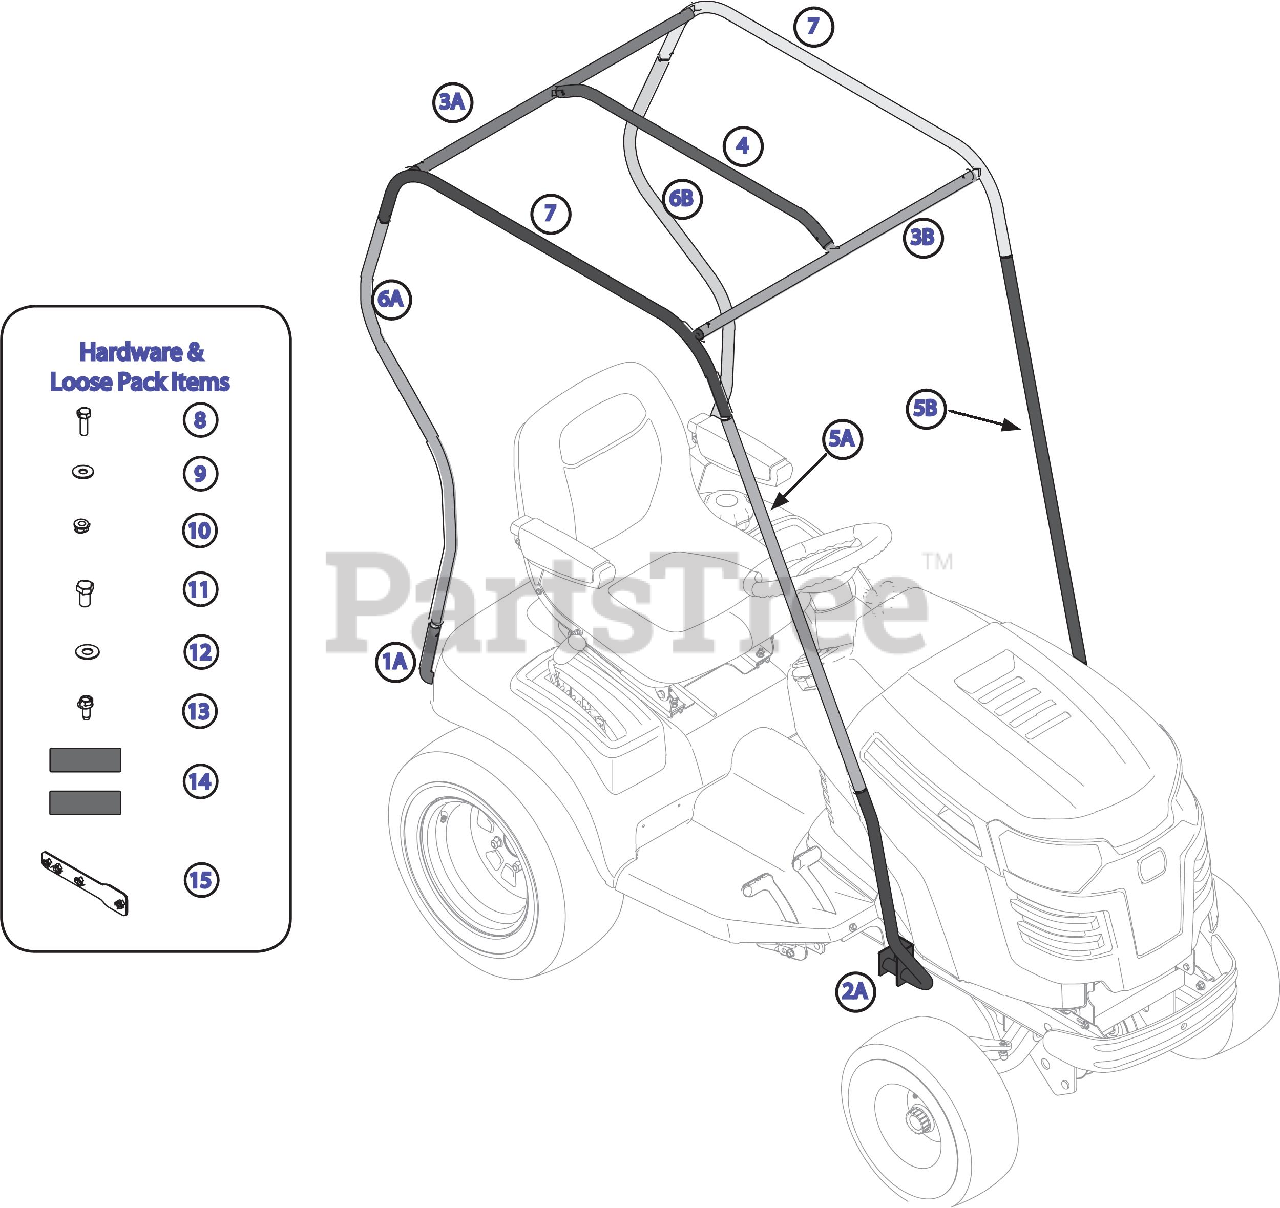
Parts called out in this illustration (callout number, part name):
1A	Rear Bottom Right Support
1A	Rear Bottom Left Support (NS)
2A	Right Front Bottom Support
2A	Left Front Bottom Support (NS)
3A	Rear Top Cross Support
3B	Front Top Cross Support
4	Top Center Support
5A	Front Right Side Support
5B	Front Left Side Support
6A	Right Rear Side Support
6B	Left Rear Side Support
7	Top Side Support
8	Hex Screw, 5?16-18: 1.0
9	Washer, .343 x .800 x .062
10	Flange Lock Nut, 5?16-18
11	Hex Screw, 7/ 16-14: .750
12	Flat Washer, .444 x 1.0 x .057
13	Hex Screw, 5?16-18: .75
14	Reflector Labels
15	Mounting Bracket
NS	Spring Button Clip
NS	Snow Cab XT-3
NS	Sun Shade
